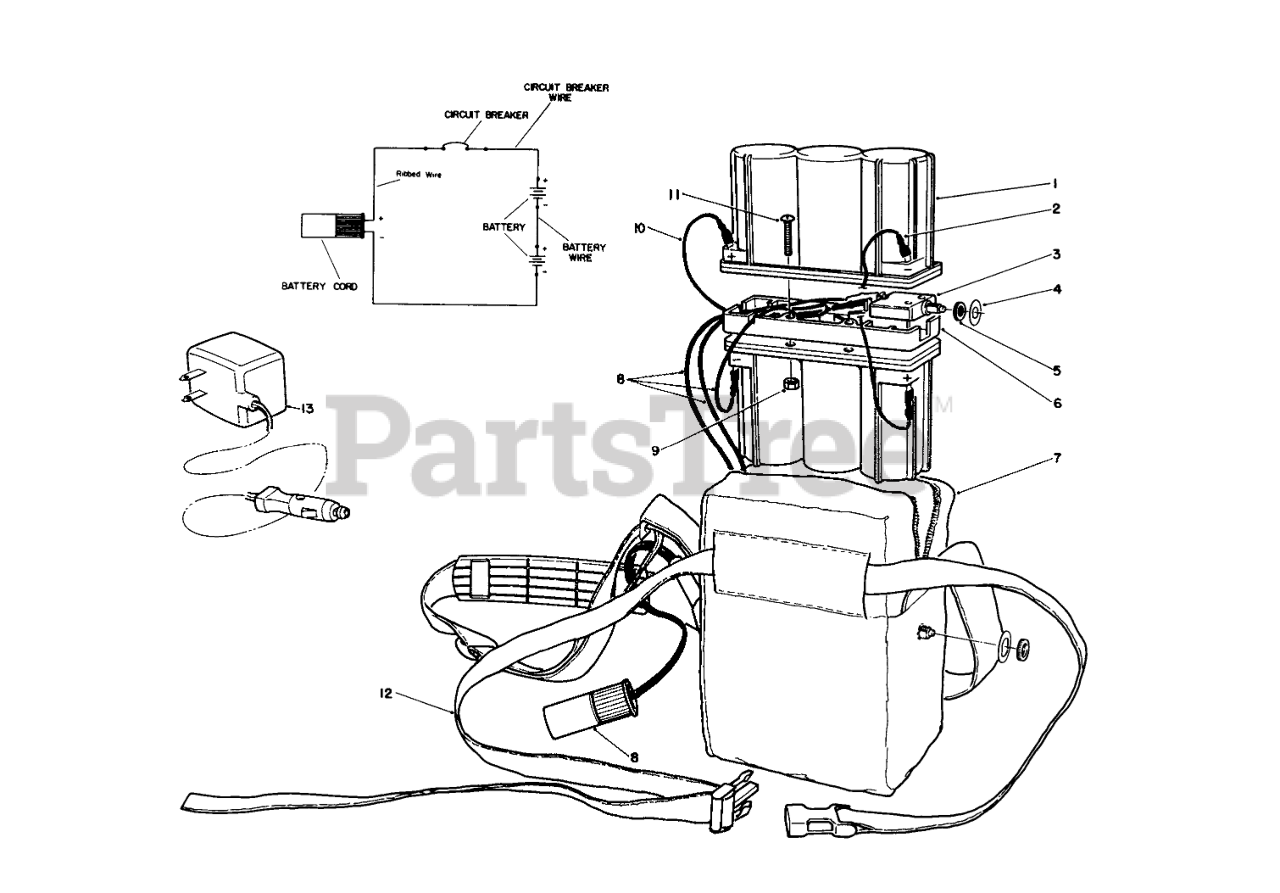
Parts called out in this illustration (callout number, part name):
1	BATTERY, 6 VOLT
2	WIRE ASSEMBLY-BATTERY
3	CKT BREAKER 15 AMP 125V
4	CIRCUIT BREAKER PLATE
5	KNURLED NUT
6	BATTERY SPACER
7	Pack-Soft
8	CORD-BATTERY PACK
9	NUT-HEX
10	WIRE ASSY-CIRCUIT BREAK
11	SCREW-PPH
12	BELT-WAIST
13	Charger 12 Volt
